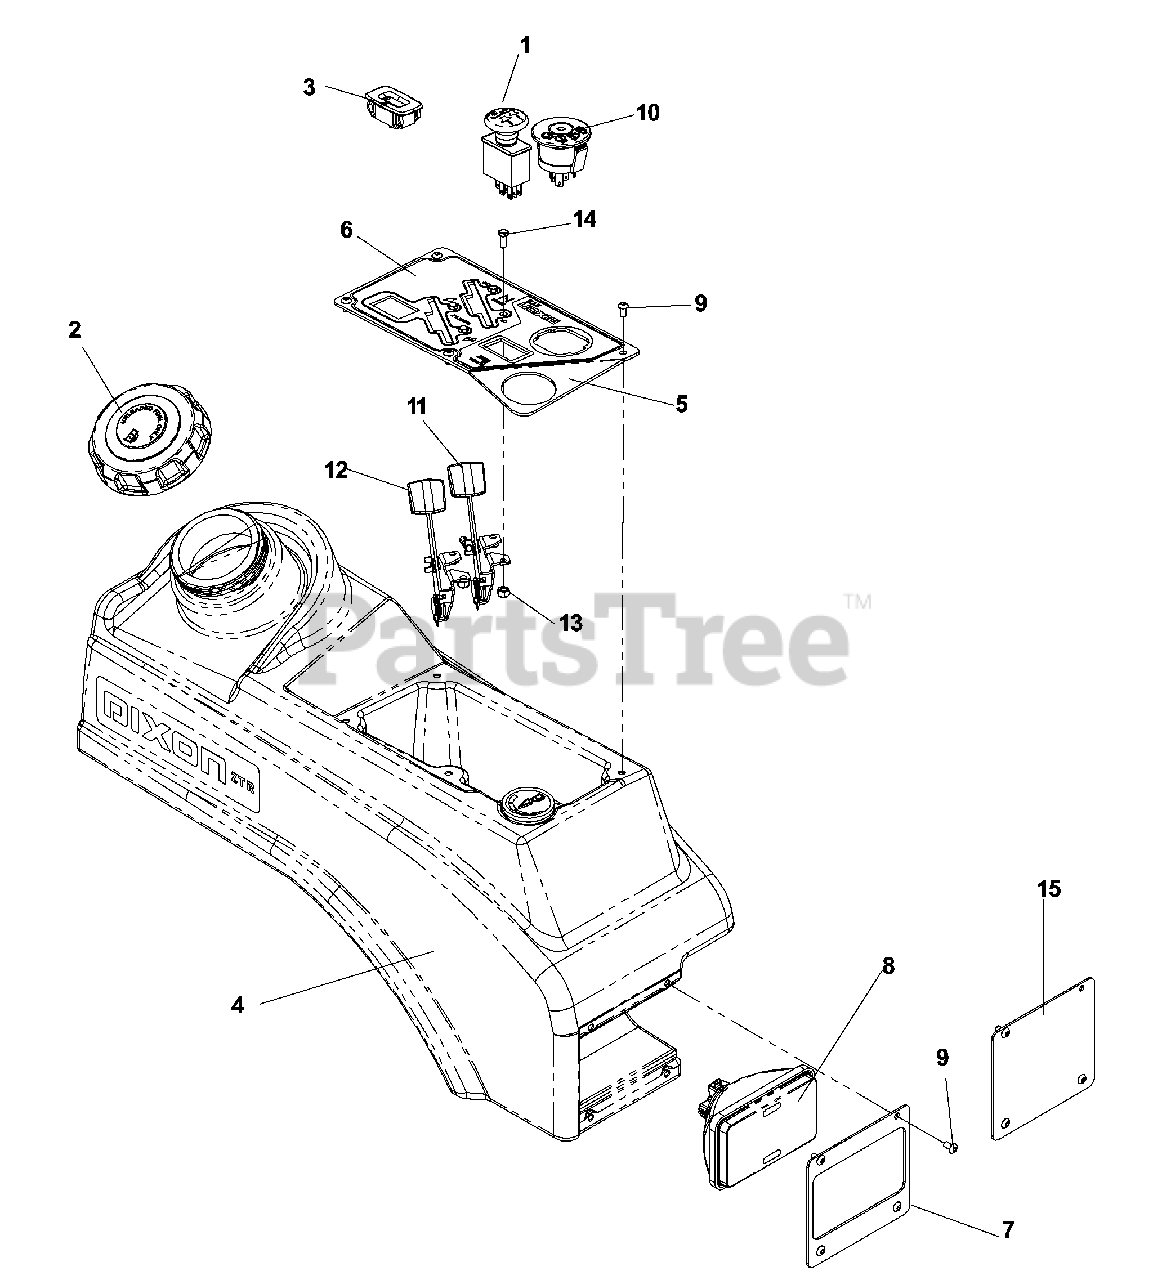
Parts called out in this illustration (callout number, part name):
1	SWITCH, BLADE
2	FUEL CAP ANTI-SPLASH
3	HOUR METER
4	TANK, FUEL, RT
5	CONTROL PANEL
6	DECAL, CONTROL
7	PLATE LIGHT
8	LIGHT
9	SCR #10-24 X 3/8 SKT HD BLK OX
10	IGNITION SWITCH
11	CABLE CHOKE
12	CABLE THROTTLE
13	NUT 10-24 NYLOC
14	HCS #10-24 X 1/2
